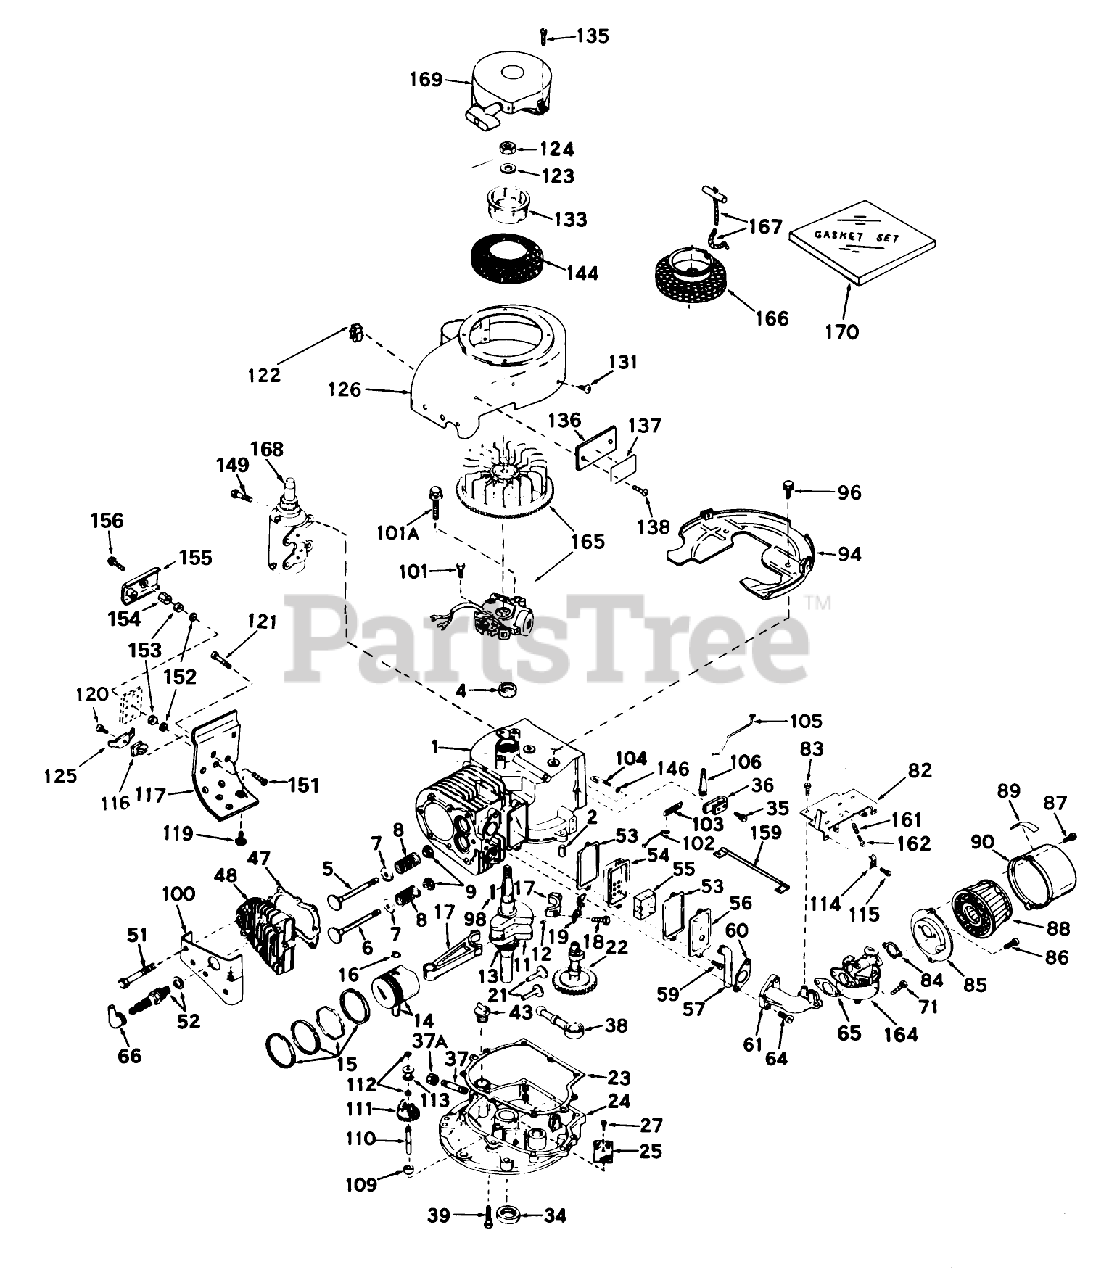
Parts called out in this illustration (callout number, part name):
1	Cylinder Assy. (Incl Nos. 2 4)
2	Pin-Dowel
4	Oil Seal
5	Valve, Intake (Standard)(Incl. No. 9)
5	Valve, Intake (1/32" oversize)(Incl. No. 9)
6	Valve, Exhaust (Standard)(Incl. No. 9)
6	Valve, Exhaust (1/32" oversize)(Incl. No. 9)
7	Cap-Spring, Valve
8	Spring-Valve
9	Keeper-Spring, Valve
11	Crankshaft Assy. (Incl. Nos. 12 13)
12	Pin, Groove
13	Gear-Crankshaft
14	Piston Pin Assy. (Incl. 2 of No. 16)(Standard)
14	Piston Pin Assy. (Incl. 2 of No. 16)(.010 oversize)
14	Piston Pin Assy. (Incl. 2 of No. 16)(.020 oversize)
15	ORing
15	Ring Set (.010" OS)
15	Ring Set (.020" OS)
17	Rod Assy., Connecting (Incl. Nos. 10 18)
18	Screw, Hex Hd.
19	Plate, Lock
21	Lifter Valve
22	Screw
23	Gasket-Cover, Cylinder
24	B Flange Assy., Mounting (Incl. Nos.25, 27, 34, 43 110)
25	Screen-Oil Filter
27	Screw
34	Seal-Oil
35	Screw
36	Clamp-Lever, Governor
37	Nipple, Pipe
37A	Cap-Pipe
38	Pump, Oil
39	Screw (1/4-20 x 1-1/4)
43	Plug-Fill, Oil
47	Gasket-Cylinder Head
48	CYLINDER HEAD
51	Screw Hex Hd. Cap
52	SPARK PLUG
53	Gasket-Breather
54	Body-Breather
55	Element-Breather
56	Cover-Valve
57	Tube-Breather
59	Screw
60	Gasket-Intake
61	Pipe-Intake
64	Screw (T-30, 5/16-18x1-3/32)
65	Gasket
66	Cover-Spark Plug
71	Screw-Hex Hd.
82	Control Assy., Speed (Incl. Nos. 161 162)
83	Screw (10-24 x 9/16)
84	Gasket
85	Bracket
86	Screw (10-32 x 1/2)
87	Screw
88	Element
89	Decal
90	Body
94	Baffle Blower Housing
96	Screw (1/4-20x19/32)
98	Key-Flywheel
100	Cover-Head, Cylinder
101	Screw
101A	Screw, Hex Hd. Cap, Sems
101A	Screw
102	Link Governor Spring
103	Spring Governor
104	Rod, Governor (Incl. Nos. 146)
105	Link Governor
106	Lever-Governor
109	Spacer
110	Shaft, Governor
111	Governor Gear ASM
112	Ring-Retaining
113	Spool-Governor
114	Conduit
115	Screw (10-32 x 3/8)
116	Grommet
117	Emnsion, Blower Housing
119	Screw
120	Screw
121	Screw
122	51004 GIL ROTARY TI
123	Washer
125	Terminal, Ground
126	Housing, Blower
131	Screw, Hex Hd.
133	Cup-Starter
135	Screw
136	IDENTIFICATION PLATE
137	480B GIL SNWTHWR O/
138	DRIVE STUD
144	Screen, Air
146	Washer-Flat
149	Screw
151	56008 ADN.KIT 28727
152	Lockwasher (Model V70-125149)
153	33144C/45C/49A/53A
154	Nut, Long (Model V70-125149)
155	Cover, Panel
156	Screw
159	Wire, Ground
161	Spring-Compression
162	Screw
164	Carburetor
165	Magneto
165	Magneto, Alternator (Model V70-125149)
166	Hub Screen, Rope Starter
167	Rope Assy., Starter
168	Motor, Starter
169	Starter, Rewind
170	Gasket Set
